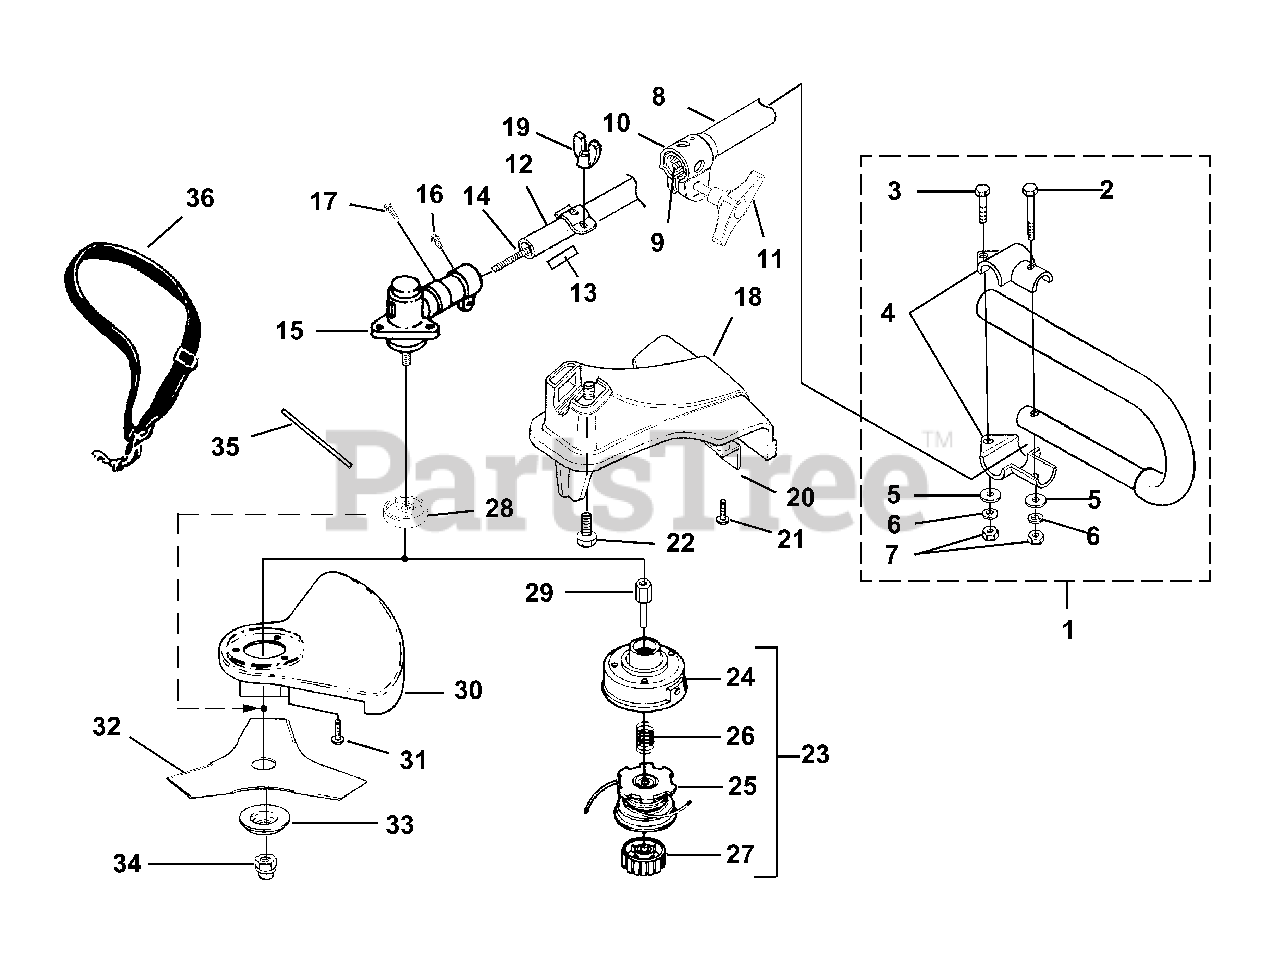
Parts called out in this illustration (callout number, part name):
1	HANDLE("J")
2	SCREW-Hex Hd. (1/4-20 X 1 1/2")
3	SCREW-Hex Hd. (1/4-20 X 1")
4	CLAMP-Handle Bar
5	WASHER-Flat (1/4")
6	WASHER-Lock (1/4")
7	NUT-Hex (1/4-20)
8	DRIVESHAFT HOUSING (Upper)
9	FLEXSHAFT-w/Collar & Liner
10	COUPLER KIT
11	KNOB
12	DRIVESHAFT HOUSING (Lower)
13	DECAL-Warning
14	SHAFT-Flexible
15	GEAR HEAD
16	Screw, Cap Hd. (1/4-20 X 7/8")
17	Screw-Hex Hd. (10-24 x 1/2")
18	GRASS DEFLECTOR KIT
19	WING NUT
20	BLADE-Cut-Off
21	SCREW, Thread Form. (10-24 X 3/4")
22	SCREW-Square Head
23	STRINGHEAD-Complete (.095")
24	HOUSING & EYELET (Dual Line)
25	SPOOL & STRING (.095")
26	SPRING-Compression
27	RETAINER-Spool (L.H. Thread, Red)
28	WASHER-Flanged
29	ADAPTER-Shaft
30	BLADE GUARD
31	SCREW
32	BLADE-Tri-Arc(TM)
33	WASHER-Cupped (Lower)
34	NUT-Hex (L.H.)
35	TOOL-Holding Pin
36	HARNESS
